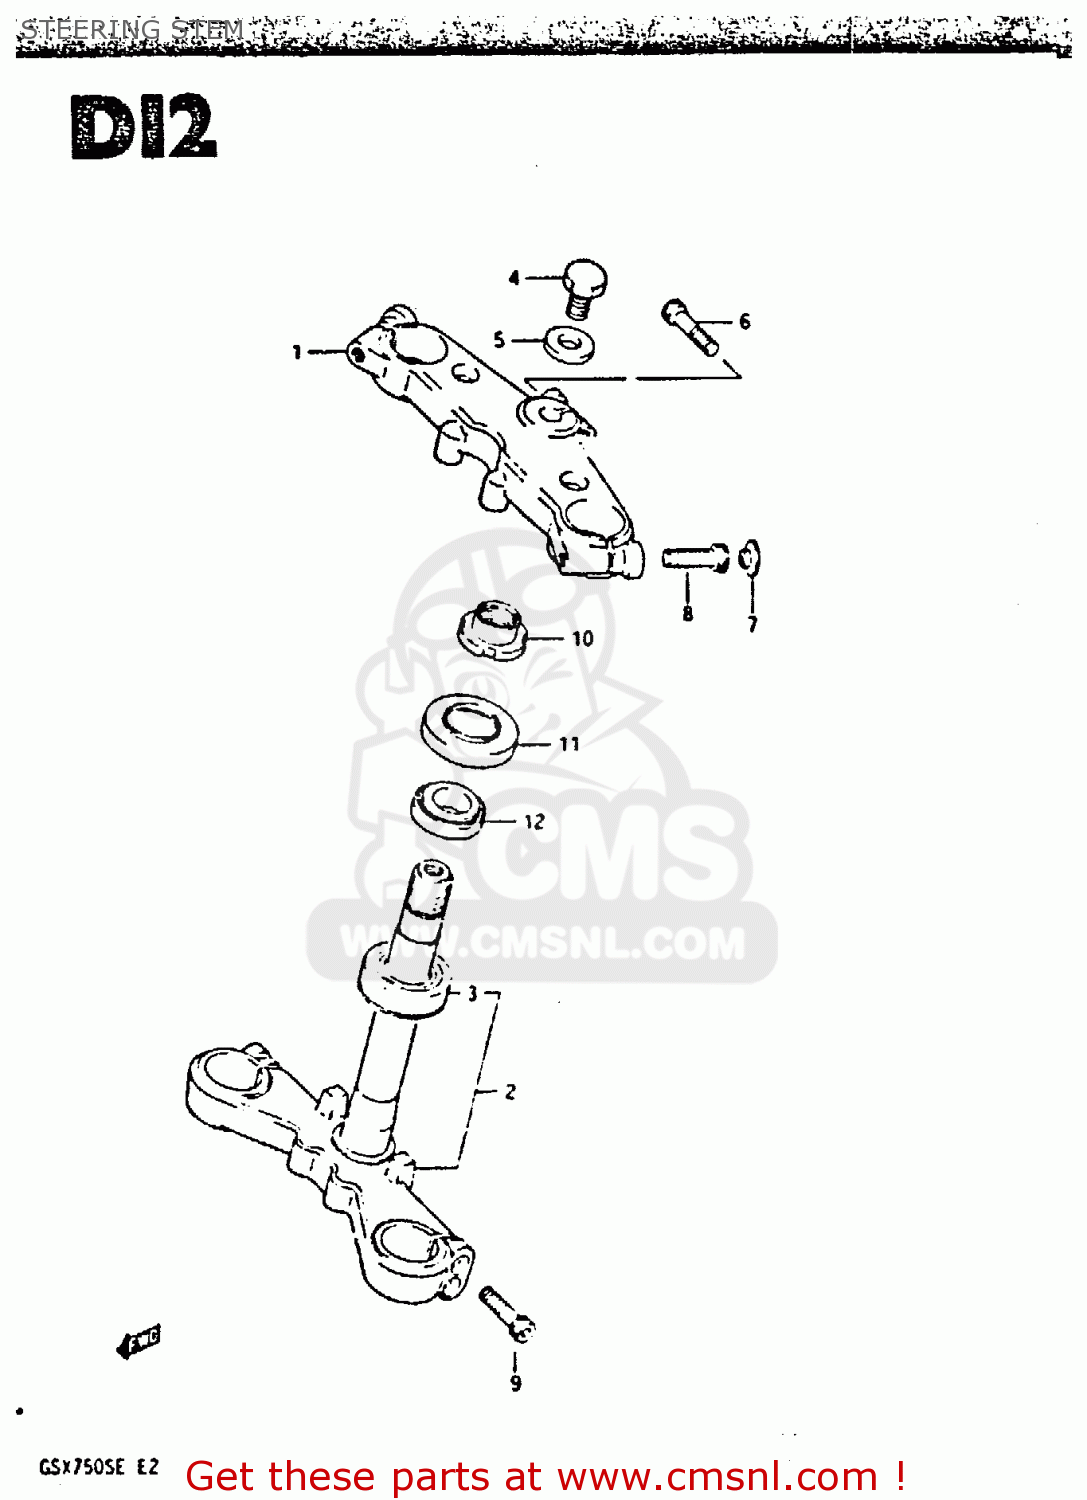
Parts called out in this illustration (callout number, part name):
1	STEM HEAD, STEERING (BLACK)
2	STEM, STEERING (BLACK)
3	BEARING
4	NUT,STEM HEAD
5	WASHER,STEERING STEM B
6	BOLT 8X35
7	CAP(OD:20)
8	BOLT
9	BOLT 8X35
10	NUT,STEERING STEM
11	DUST SEAL,STEERING UPR
12	TAPER,ROLLER BEARING
